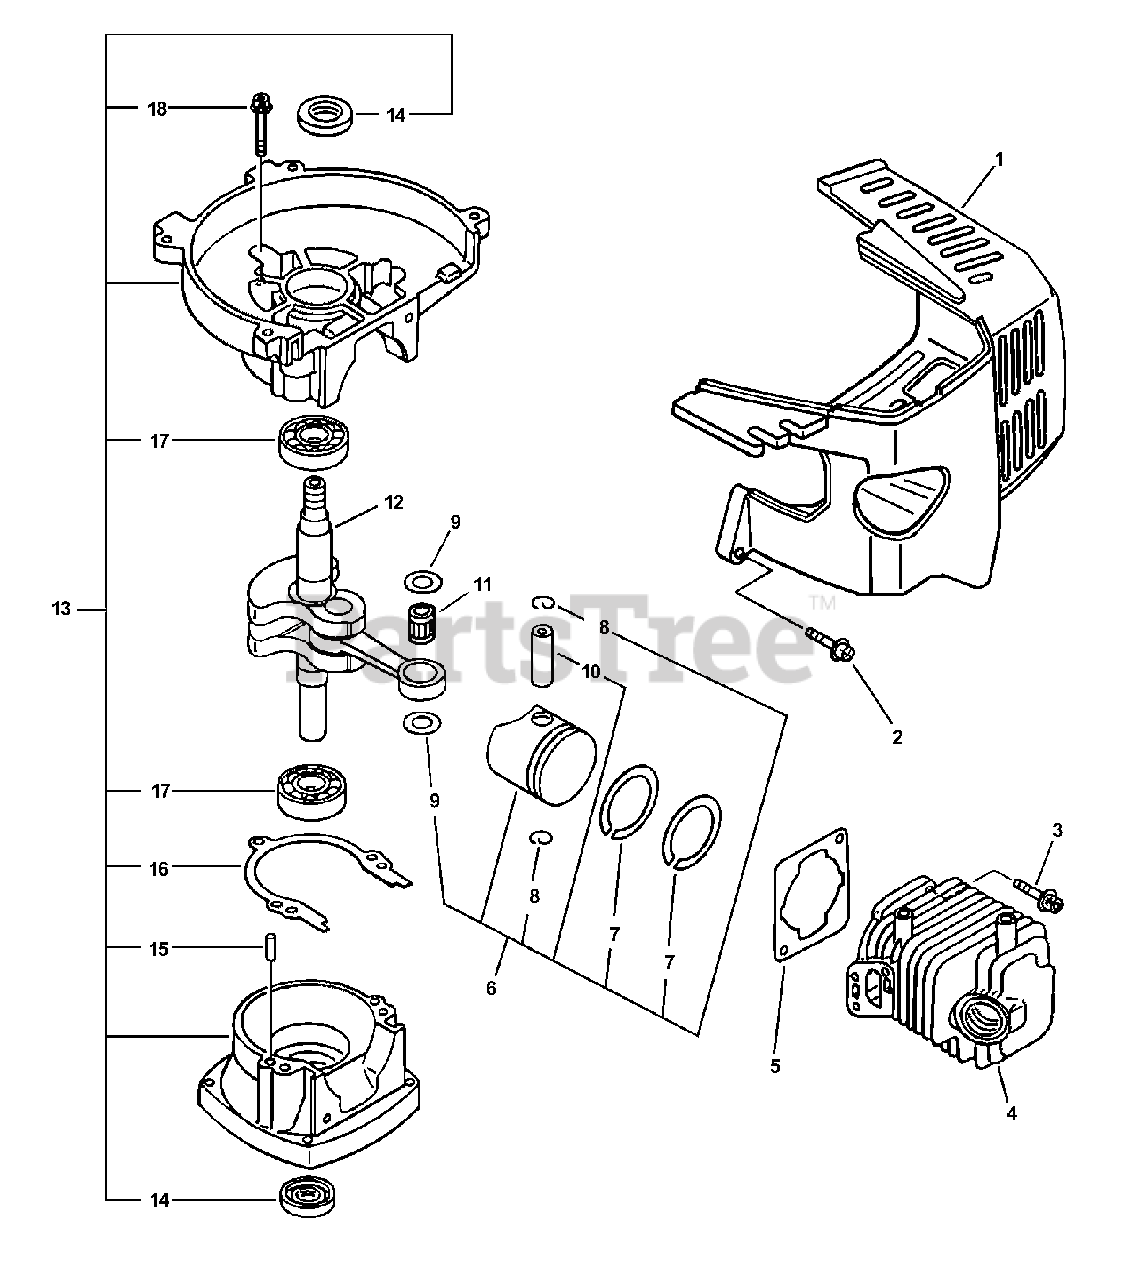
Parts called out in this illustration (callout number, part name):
1	COVER, ENGINE
2	SCREW 4×22
3	BOLT 5×22
4	CYLINDER
5	GASKET, CYLINDER
6	PISTON KIT
7	RING, PISTON
8	RING, SNAP
9	WASHER, THRUST
10	PIN, PISTON 8
11	BEARING, NEEDLE
12	CRANKSHAFT ASSY
13	CRANKCASE KIT
14	SEAL, OIL 12
15	PIN, LOCATING 4
16	GASKET, CRANKCASE
17	BEARING, BALL - 6201 C3
18	BOLT 5×28
